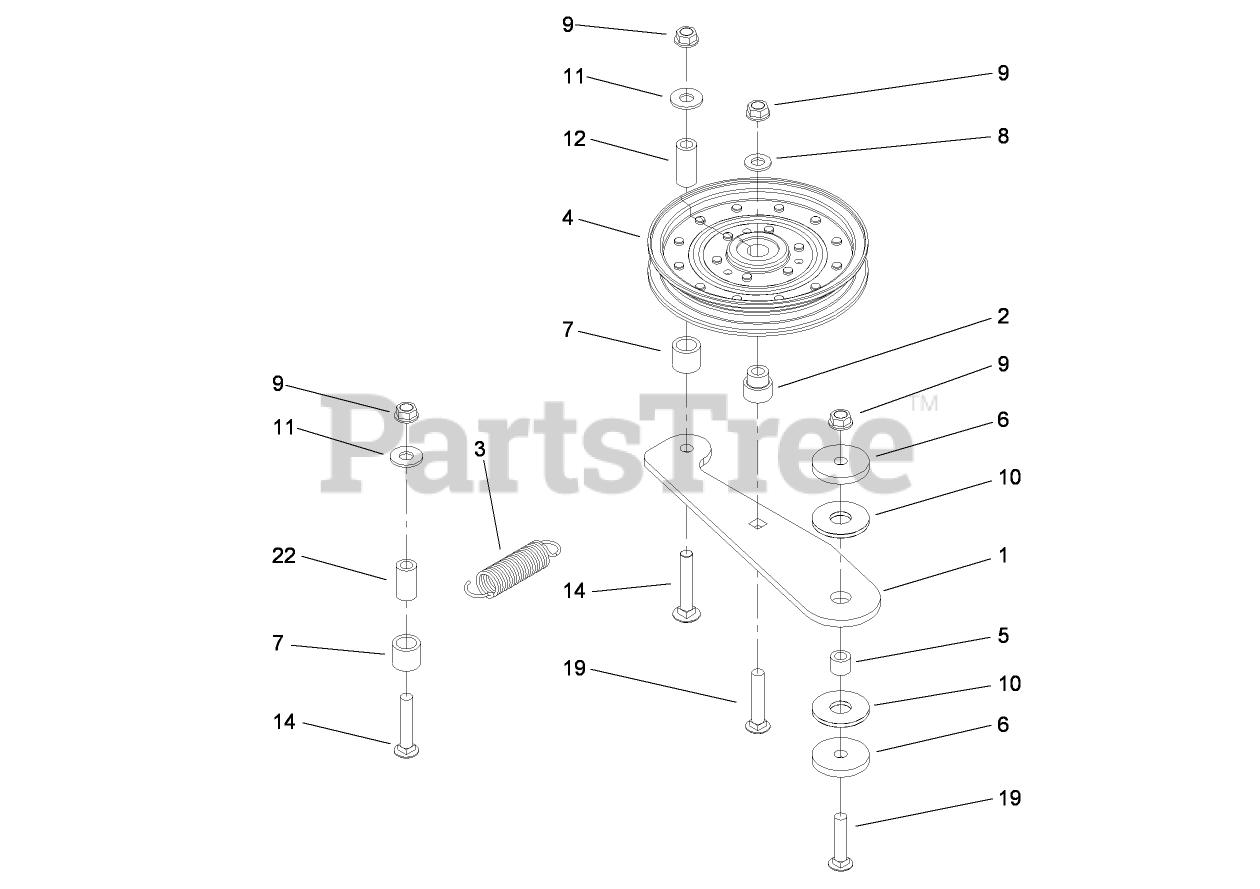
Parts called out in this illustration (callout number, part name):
1	ARM-IDLER
2	BUSHING-IDLER
3	SPRING-EXTENSION
4	Idler-Flat
5	BUSHING-LEVER, LIFT
6	WASHER-PLAIN
7	SPACER-RUBBER
8	WASHER-FLAT
9	NUT-HHF, WHIZ
10	WASHER-FRICTION, COMPOSITE
11	WASHER-FLAT
12	SPACER
14	SCREW-CARR
19	SCREW-CARR
22	SPACER
